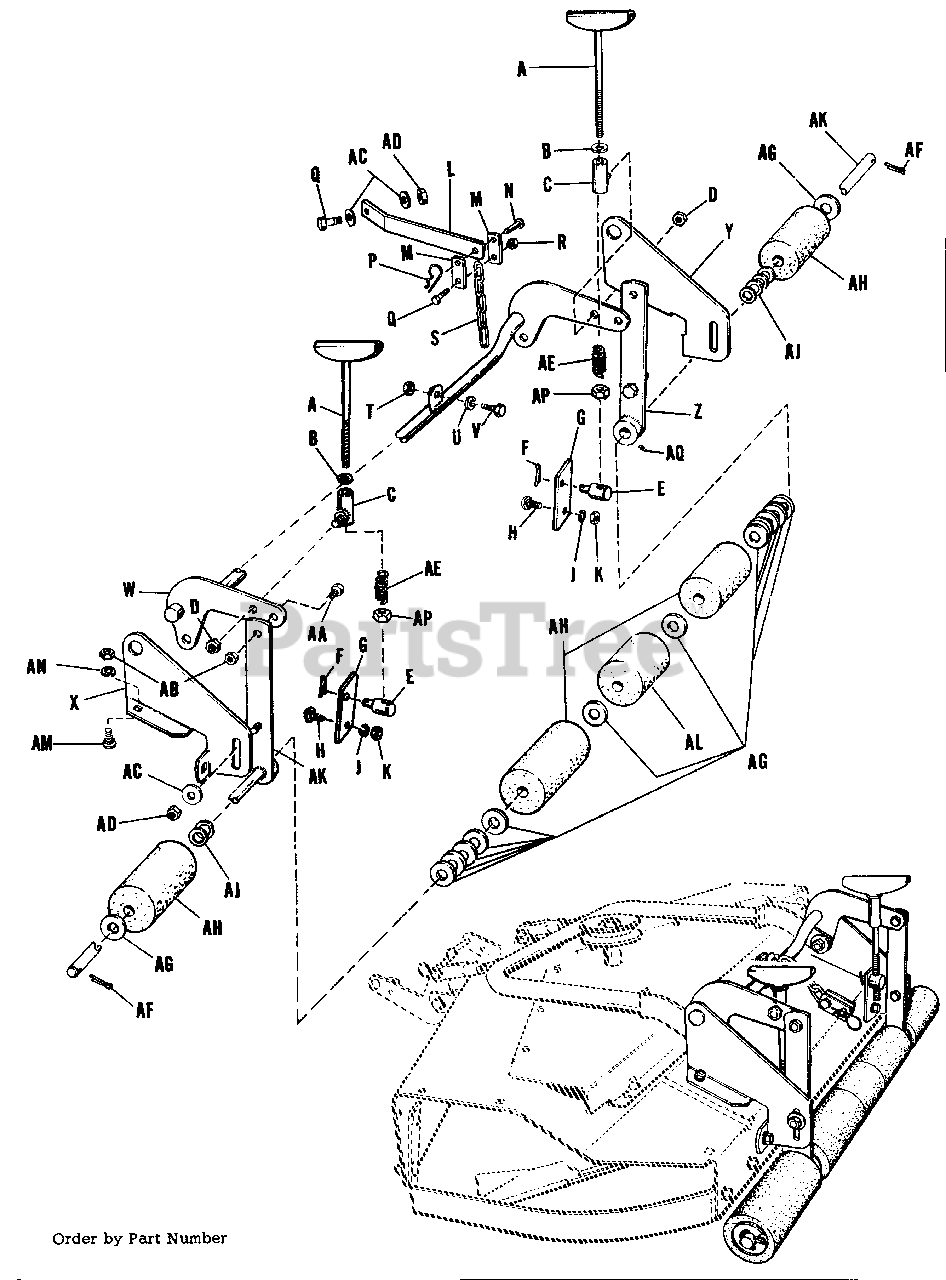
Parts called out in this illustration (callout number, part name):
A	Screw Assembly, Adjusting
B	Washer, Plain, 3/8"
C	Socket Assembly, Crank
D	Nut, Hex, Full, Lock, 3/8"-16 NC
F	Cotter Pin, 3/32" x 3/4" lg.
G	Link Lift
H	Bolt, Carriage, 3/8"-16 NC x 3/4" lg.
J	Washer, Lock, 3/8"
K	Nut, Hex, Full, 3/8"-16 NC
L	Lever, Mower Lift
M	Link, Mower Lift
P	Clip, Spring
Q	Capscrew, Hex Hd., 3/8"-16 NC x 1" lg.
R	Nut, Hex, Full, Lock, 3/8"-16 NC
T	Nut, Hex, Full, Lock, 3/8"-16 NC
U	3/8" Washer
V	Capscrew, Hex Hd., 3/8-16 x 1" lg.
W	Arm Assembly, Rocker
X	Bracket, Roller,
Y	Bracket, Roller,
Z	Bar Assembly, Roller
AA	Capscrew, Hex Hd., 3/8"-16 NC x 1" lg.
AB	Nut, Hex, Full, 3/8"-16 NC
AC	Washer, Plain, 3/8"
AD	Nut, Hex, Full, Lock, 3/8"-16 NC
AE	Spring, Adj. Screw
AF	Pin, Cotter, 3/16" x 1" lg.
AK	Shaft & Support Arm.
AM	Bolt, Carriage, 3/8"-16 NC x 3/4" lg.
AN	Washer, Lock, 3/8"
AP	Nut, Hex. Full
AQ	Set Screw
